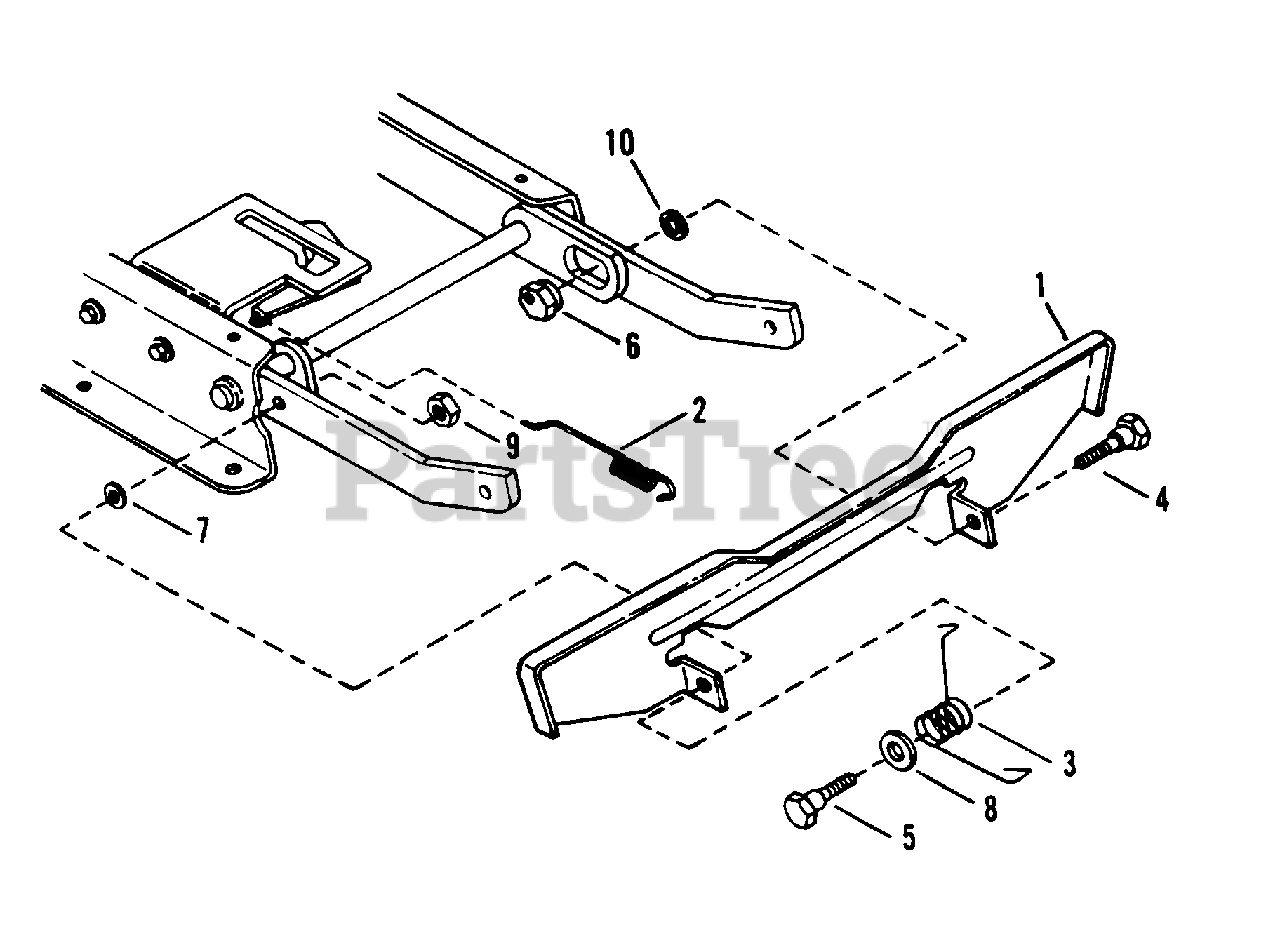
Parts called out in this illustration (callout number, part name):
1	PEDAL, Blade Stop Control
2	SPRING, Latching
3	SPRING, Pedal
4	BOLT, 3/8-24 x 3/4" Shoulder
5	BOLT, 3/8-24 x 9/16" Shoulder
6	ECCENTRIC, Leveling
7	WASHER, 3/8" Flat
8	WASHER, 1/2 Flat
9	NUT, 3/8-24 Hex Lock
10	WASHER, 3/8 Internal Tooth Lock
